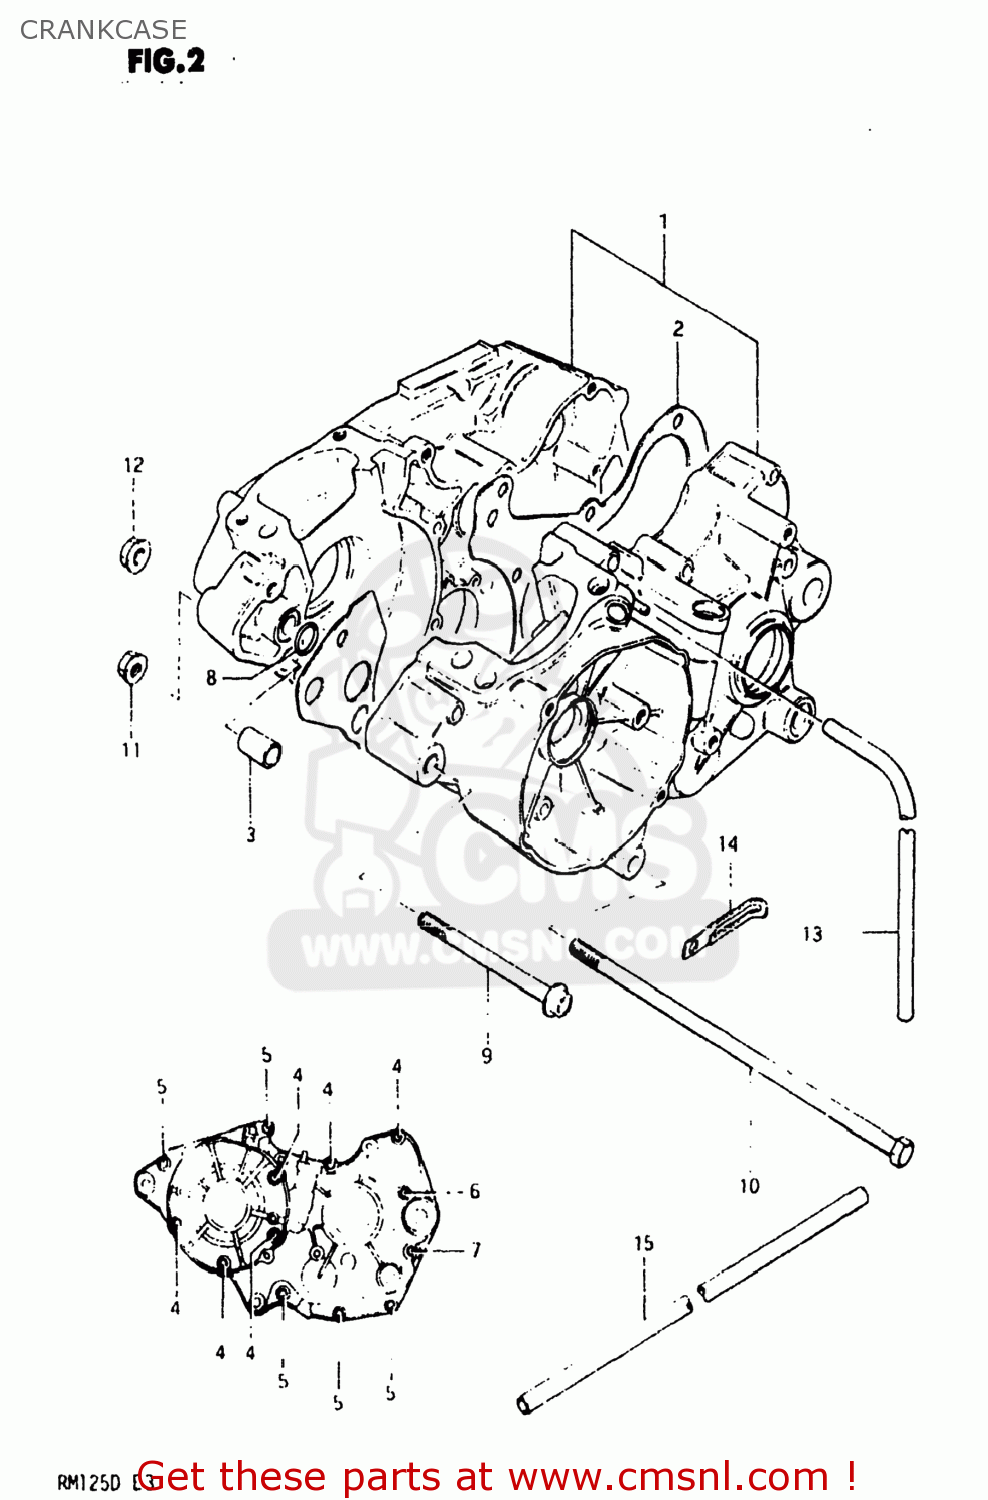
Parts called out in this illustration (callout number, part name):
1	CRANKCASE SET
2	GASKET,CRANKCASE (MCA)
3	PIN
4	SCREW (6X45)
5	SCREW
6	SCREW 6X65
7	SCREW 6X65
8	O RING(D:1.9,ID:13.8)
9	BOLT 8X90
10	BOLT 8X205
11	NUT
12	NUT
13	HOSE
14	CLAMP
15	HOSE
